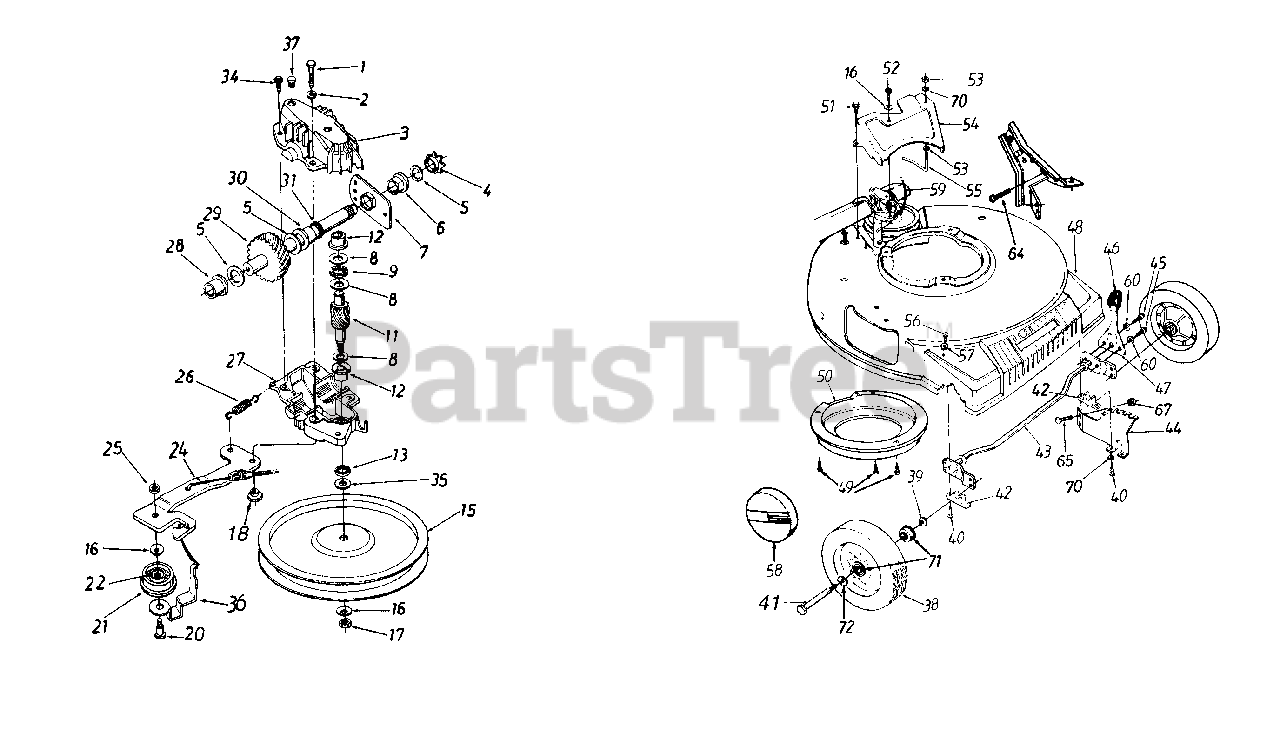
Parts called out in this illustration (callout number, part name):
1	Hex Patch Bolt 1/4-20 x 1.25"
2	L-Wash. 1/4" I.D.
3	Upper Hsg. Half
4	#48 Sprocket 7 T x 1/2 Pitch
5	Fl-Wash. 5/8" I.D. x .030
6	Hex Flange Brg..631" I.D.
8	Thrust Wash. .382" I.D. x .70" O.D.
9	Thrust Bearing .375" I.D. x .812" O.D.
11	11 Tooth Pinion Shaft
12	Flange Bearing
13	Oil Seal
15	Fl-Pulley 5.06" O.D.
16	Bell-Wash..265" I.D. x .75"
17	Hex L-Nut 1/4-28 L.H.Thd.
18	Shld. Spacer .375" Dia. x .170
20	Shld. Bolt.375" Dia. x .40"
21	Fl-Idler Plastic 1.50" Dia.
22	Needle Brg..375" x .31
24	Idler Brk't. Ass'y.
25	Hex Patch L-Nut 1/4-28 Thd.
26	Extension Spring 1.12" Lg.
27	Lower Hsg. Half
28	Flange Bearing .566 Dia.
29	Shaft Ass'y.
30	Flange Bearing .629 Dia.
31	Oil Seal .625 Dia.
34	Hex B-Tap Scr. #10 x .62"
35	Hex Washer .26" x .88"
36	Belt Keeper
37	Plug 1/4 x .437"
38	Wheel Ass'y. Comp. (Gray Rim)
39	Bell-Wash..380" I.D. x .88
40	Hex Wash. Hd. Scr. 1/4 x 1" Lg.
41	Front Axle Bolt
42	Block Bushing
45	Hex TT-Tap Scr. 1/4-20 x .38"
46	Knob
47	Spring Lever
48	Plastic Front End (Black)
49	Hexindwsh 1/4 x .50"
52	Hex Wash. Hd. B-Tap Scr.1/4 x .62"
53	Hex Nut 1/4-20Thd.
56	Torx Truss Hd. Scr. 5/16 x .75"
57	Bell-Wash..345" I.D. x .88"
58	Hub Cap
59	S.P.Cable
60	External L-Wash. 1/4" I.D.
65	Carr. Bolt 1/4-20 x .5" Lg.
67	Hex Flange L-Nut 1/4-20Thd.
70	L-Wash. 1/4" I.D.
71	Wheel Bearing
72	Wave Washer
